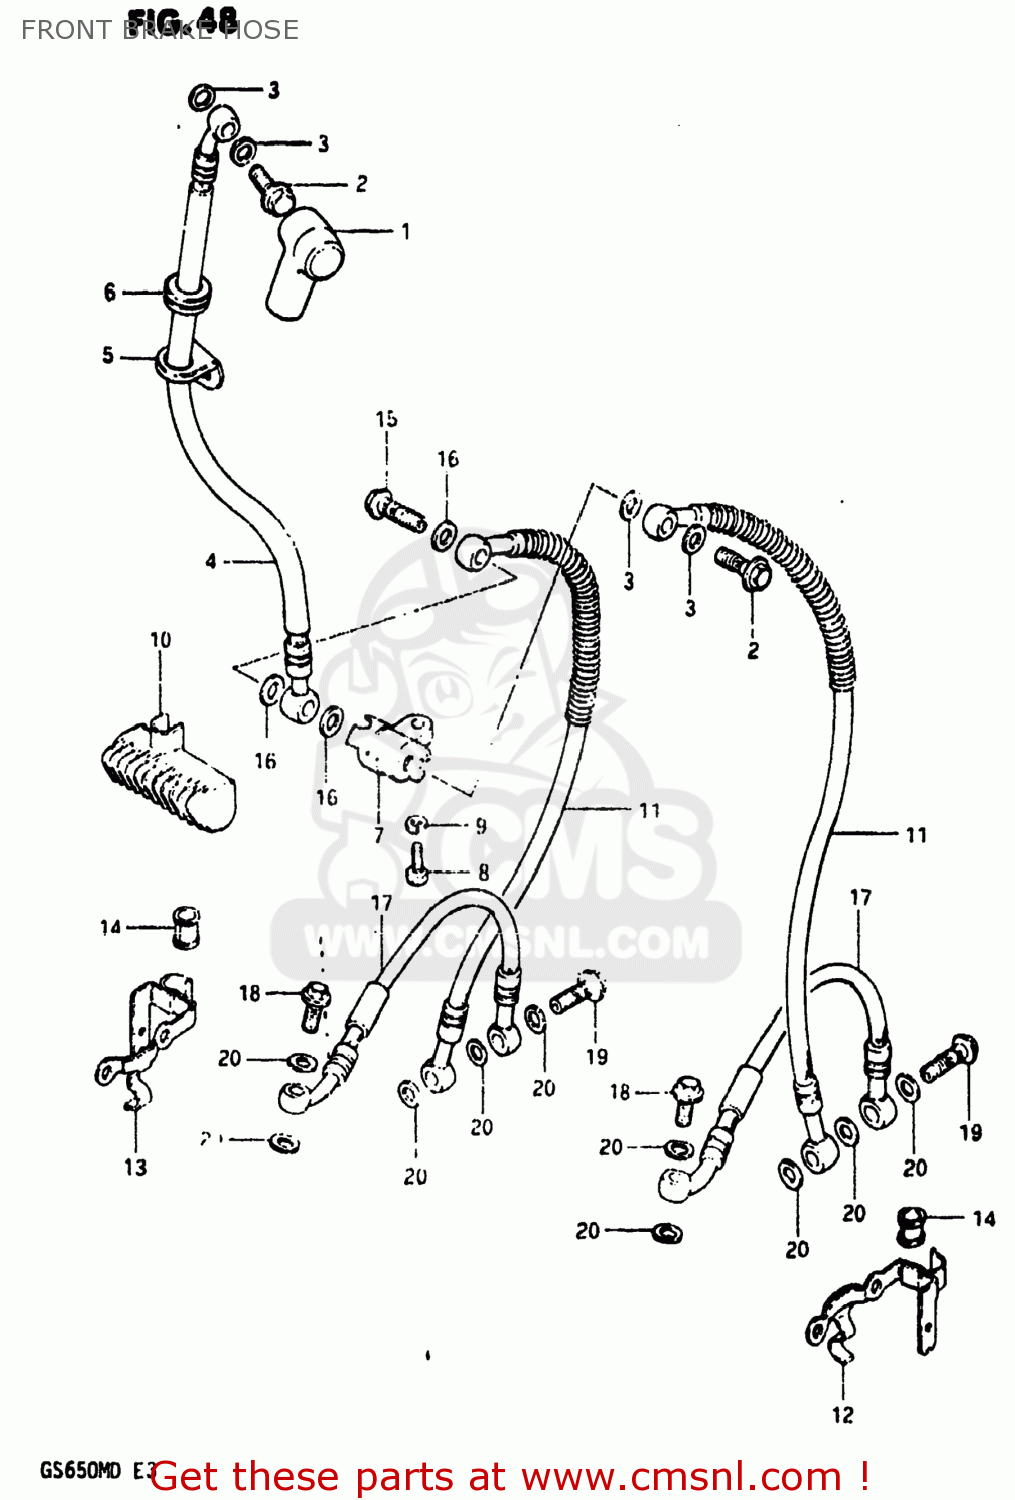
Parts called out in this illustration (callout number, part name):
1	BOOT,MASTER CYLINDER
2	BOLT UNION
3	WASHER
4	HOSE,FRONT BRAKE
5	GUIDE,BRAKE HOSE NO.1
6	GROMMET
7	JOINT,BRAKE HOSE
8	BOLT
9	LOCK WASHER
10	COVER,BRAKE HOSE JOINT
11	HOSE,FRONT BRAKE
12	CLAMP,FRONT BRAKE HOSE
13	CLAMP,FRONT BRAKE HOSE
14	BUSH,BRAKE HOSE GUIDE,NO.2
15	BOLT,UNION
16	WASHER
17	HOSE,ANTI-NOSE DIVE
18	BOLT UNION
19	BOLT,UNION
20	WASHER
